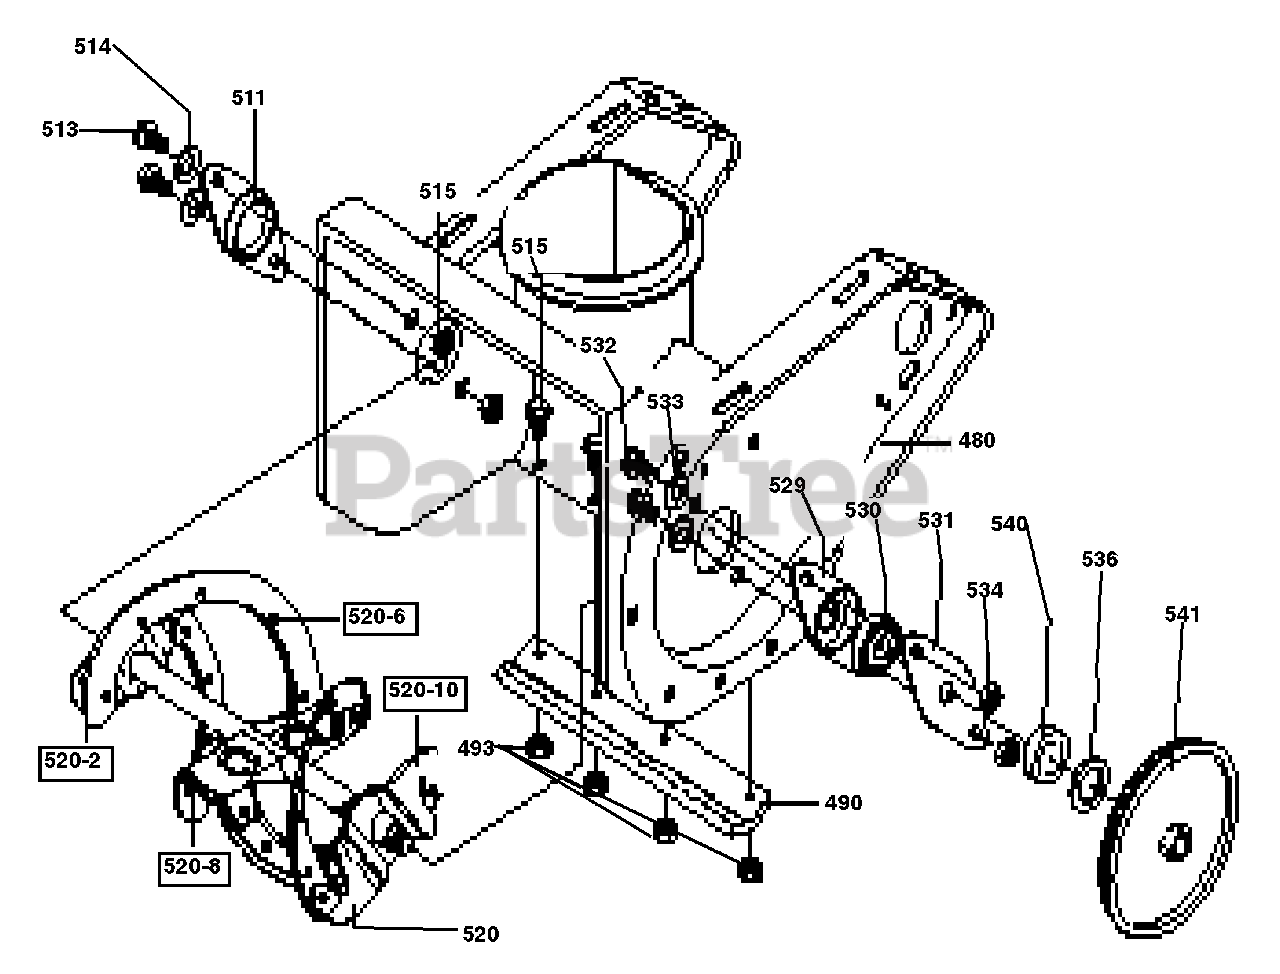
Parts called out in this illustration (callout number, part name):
480	HSNG, ASSY
490	BLADE, SCRAP
492	SCREW, 1/4-20 X .63
493	NUT, 1/4-20 WDFL MAC-LOCK
511	BEARING, FLANGE
513	SCREW, 1/4-20 X .88
514	WASHER, FLAT .281 X .63 X .065
515	NUT, 1/4-20 WDFL MAC-LOCK
520	AUGER, ASSY
520-2	BLADE, AUGER
520-6	RIVET, OVSET
520-8	BLADE CENTER
520-10	AUGER & BLADE ASSY
529	RETAINER, BEARING
530	BRNG, BALL
531	PLATE,RETAINING BEARING
532	SCREW, 1/4-20 X .62
533	WASHER, FLAT .281 X .63 X .065
534	NUT, 1/4-20 REGHEXCTRLK
536	WASHER, FLAT .640 X 1.25 X .06
540	SPACER, SLEV .640 X .88 X .15
541	PULLEY, POLYV 6" OD
